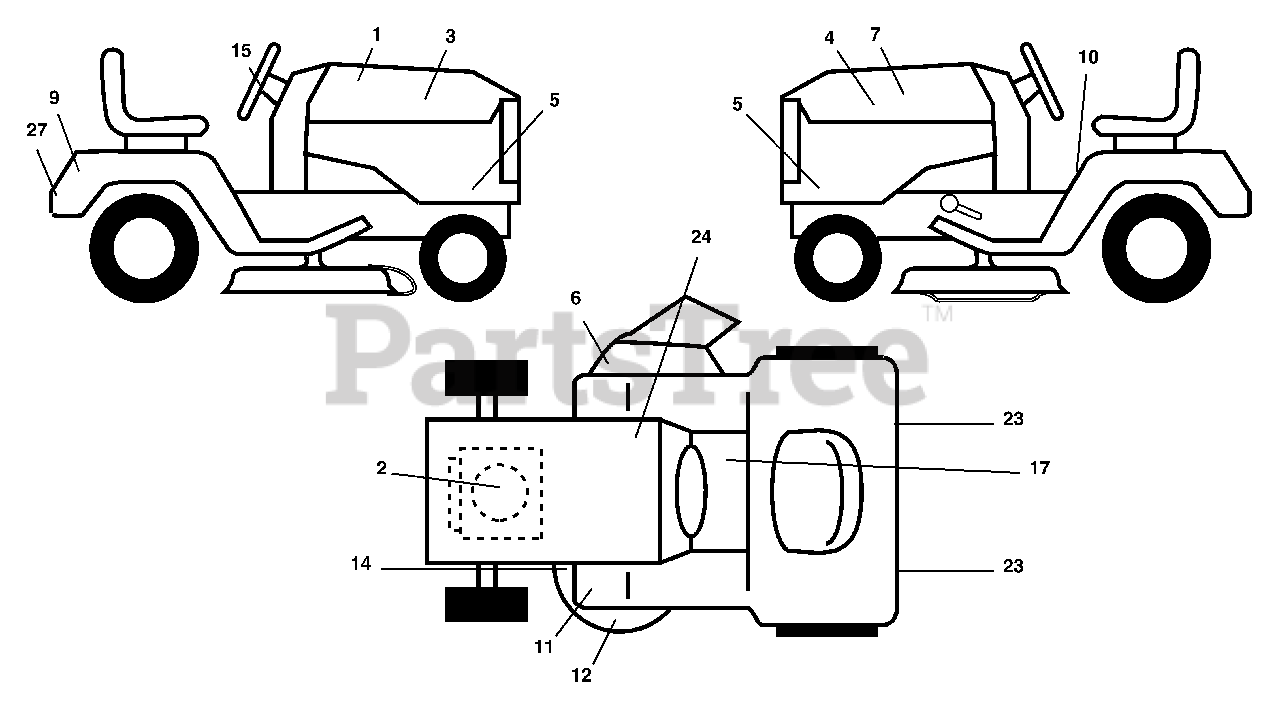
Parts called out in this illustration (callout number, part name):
1	Decal, Final
2	Decal, Engine
3	Decal, Hood, RH
4	Decal, Hood, LH
5	Decal, Side Panel
6	Decal, Warning
7	Decal, Hood Cust. Resp.
9	Decal, Fender
10	Decal, Danger
11	Decal, Foot Rest
12	Decal, Deck Caution
14	Decal, V-Belt Schematic
15	Decal, Ins. Strg Whl
17	Decal, Saddle Oper.
23	Reflector, Taillight
24	Decal, Btry Dngr/Psn
27	Decal, Drawbar
